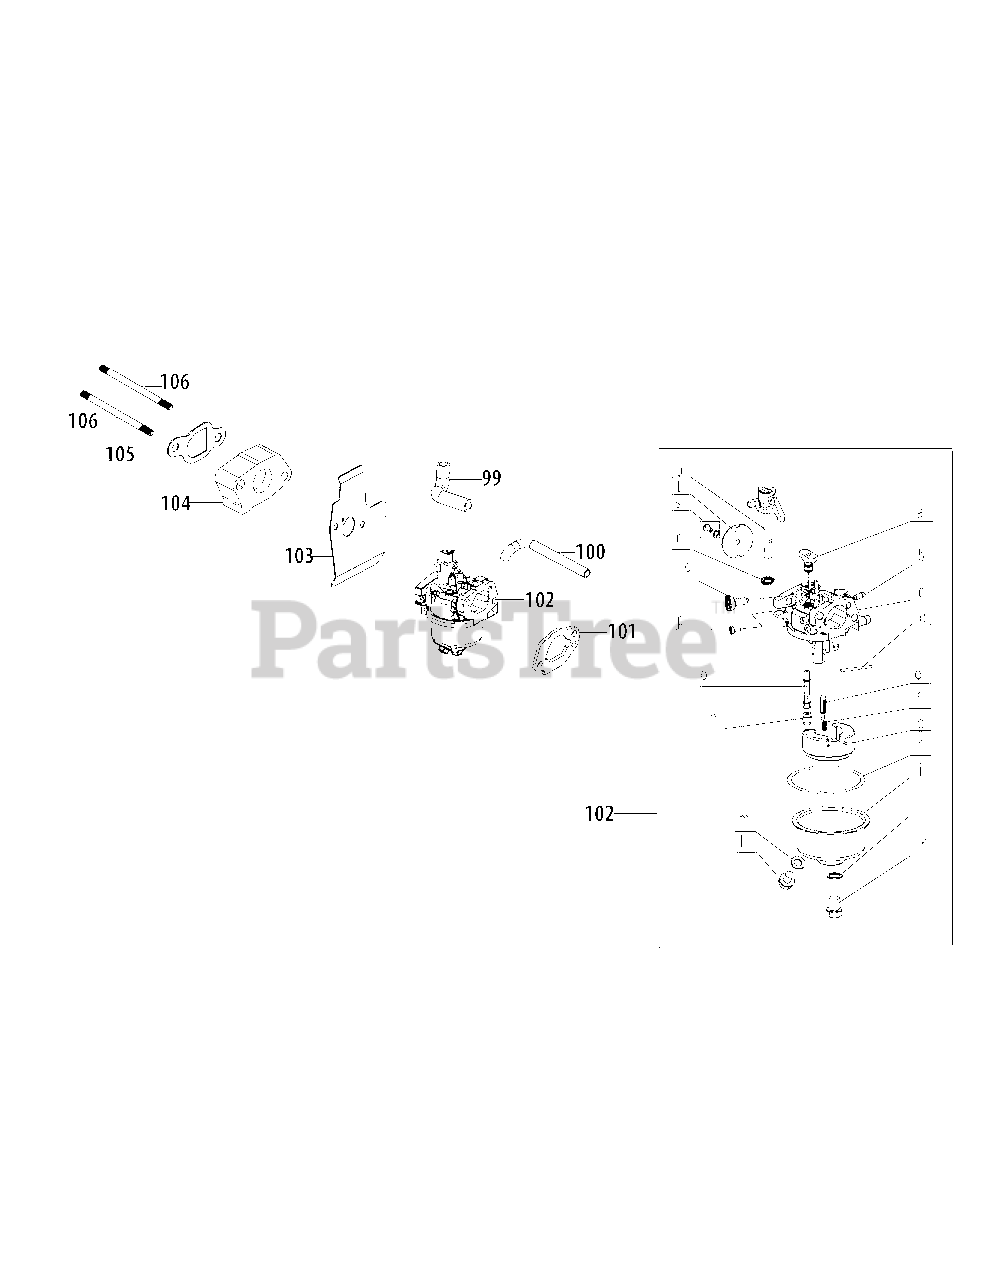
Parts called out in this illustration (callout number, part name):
99	Breather Hose
100	Primer Hose
101	Air Filter Base Gasket
102	Carburetor Assembly
103	Carburetor Gasket
104	Carburetor Insulator
105	Carburetor Insulator Gasket
106	Carb Stud M6×98
